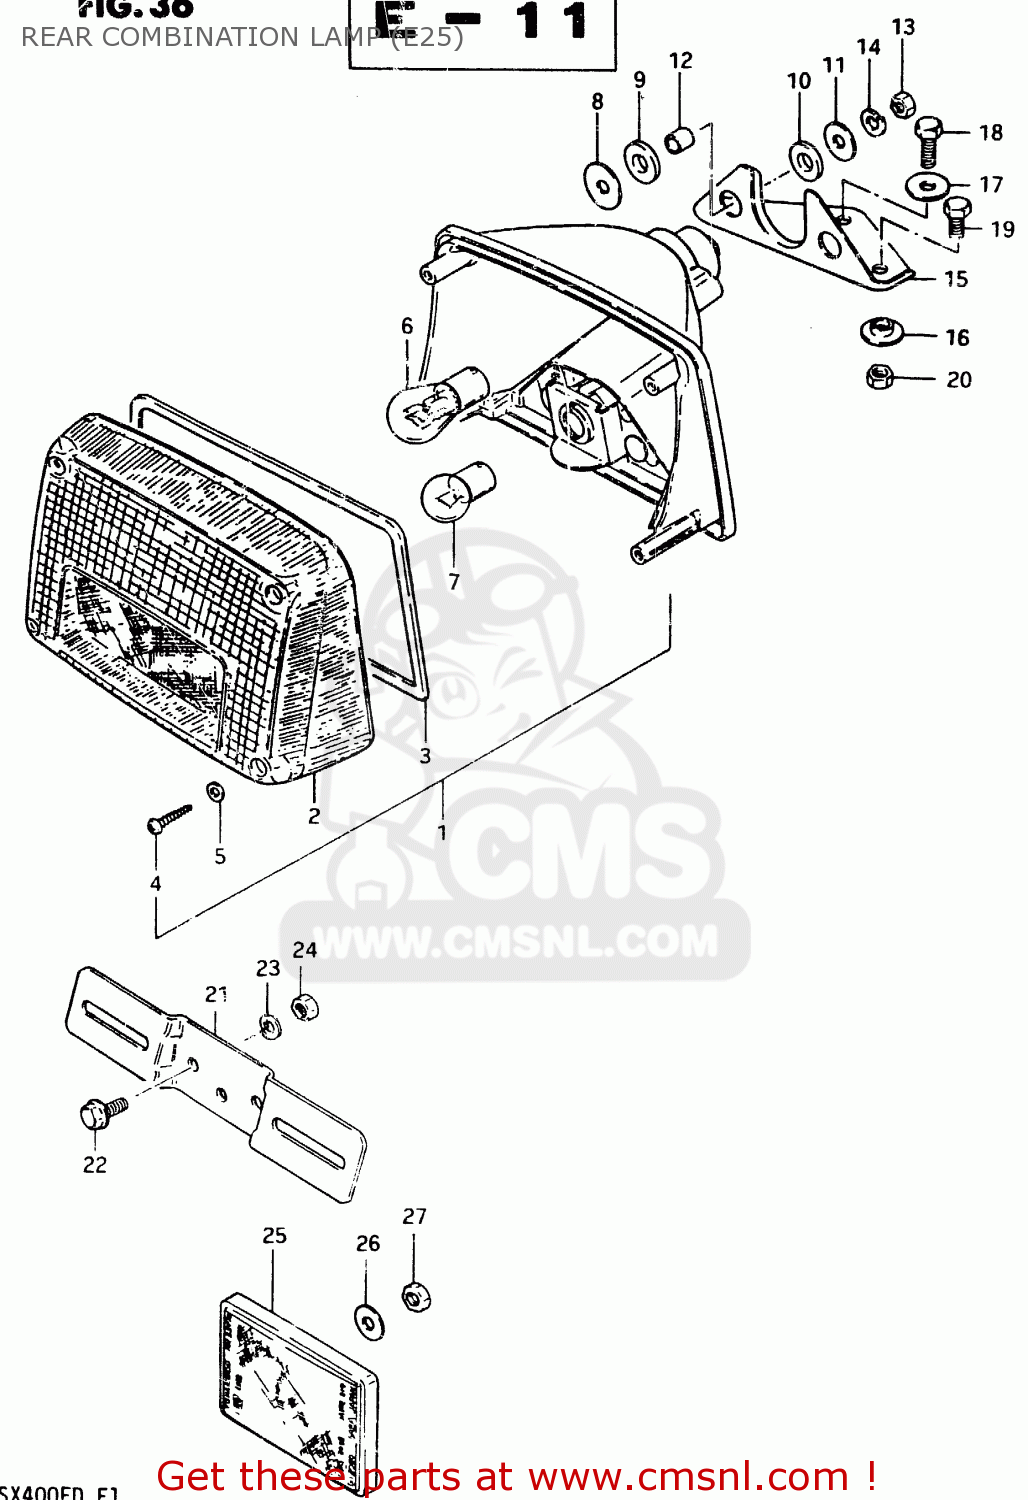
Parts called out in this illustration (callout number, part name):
1	LAMP, REAR COMBINATION
2	LENS
3	GASKET (NAS)
4	SCREW,REAR COMBINATION LAMP
5	GASKET (NAS)
6	BULB(12V21/5W)
7	BULB(12V10W,TOKAI DENSO)
8	WASHER
9	CUSHION
10	CUSHION
11	WASHER(6,5X22X1.6)
12	SPACER(6.1X9X7.5)
13	NUT
14	LOCK WASHER
15	BRACKET,RR COMBINATION LAMP
16	WASHER
17	WASHER
18	BOLT
19	BOLT, UPPER
20	NUT 6MM
21	BRACKET, LICENSE PLATE
22	BOLT
23	LOCK WASHER
24	NUT
25	REFLEX REFLECTOR,RR
26	WASHER(5.2X16X1)
27	NUT
